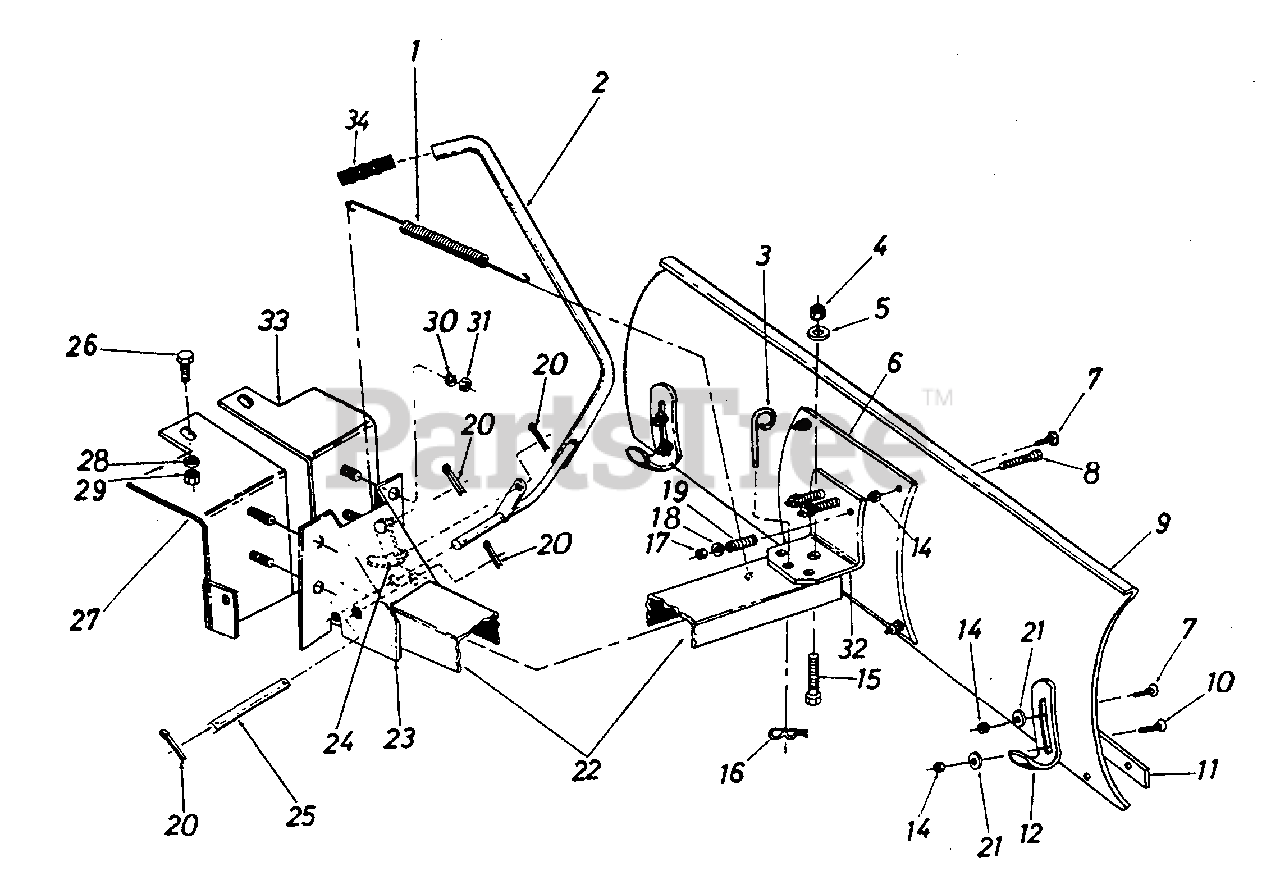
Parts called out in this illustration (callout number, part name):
1	Extension Spring
2	Lift Handle Ass'y.
3	Pivot Lock Pin
4	Hex Cent. L-Nut 1/2-13 Thd.
5	Fl-Wash. 17/32" I.D. x 1.25" Lg.
6	Reinforcement Plate
7	Carriage Bolt 5/16-18 x .75" Lg.
8	Hex Bolt 3/8-16 x 3.75" Lg. Grade 5
9	42" Blade
10	Carriage Bolt 5/16-18 x 1" Lg.
11	42" Wear Plate
12	Shoe Skid
14	Hex Cent. L-Nut 5/16-18 Thd.
15	Hex Bolt 1/2-13 x 1.25" Lg.
16	Int. Cotter Pin
17	Hex Cent. L-Nut 3/8-16 Thd.
18	Fl-Wash. 3/8" I.D.
19	Compression Spring
20	Cotter Pin 1/8" Dia. x 1" Lg.
21	Fl-Wash. 5/16" I.D.
22	Push Bar Channel
23	pivot Support Bracket
24	Lift Link
25	Channel Pivot Shaft
26	Hex Bolt 3/8-16 x 1" Lg. Grade 5
27	Support Bracket-R.H.
28	L-Wash. 3/8" I.D.
29	Hex Nut 3/8-16 Thd.
30	L-Wash. 3/8 I.D.
31	Hex Jam Nut 3/8-16 Thd.
32	Support Bracket
33	Support Bracket-L.H.
34	Rubber Grip
